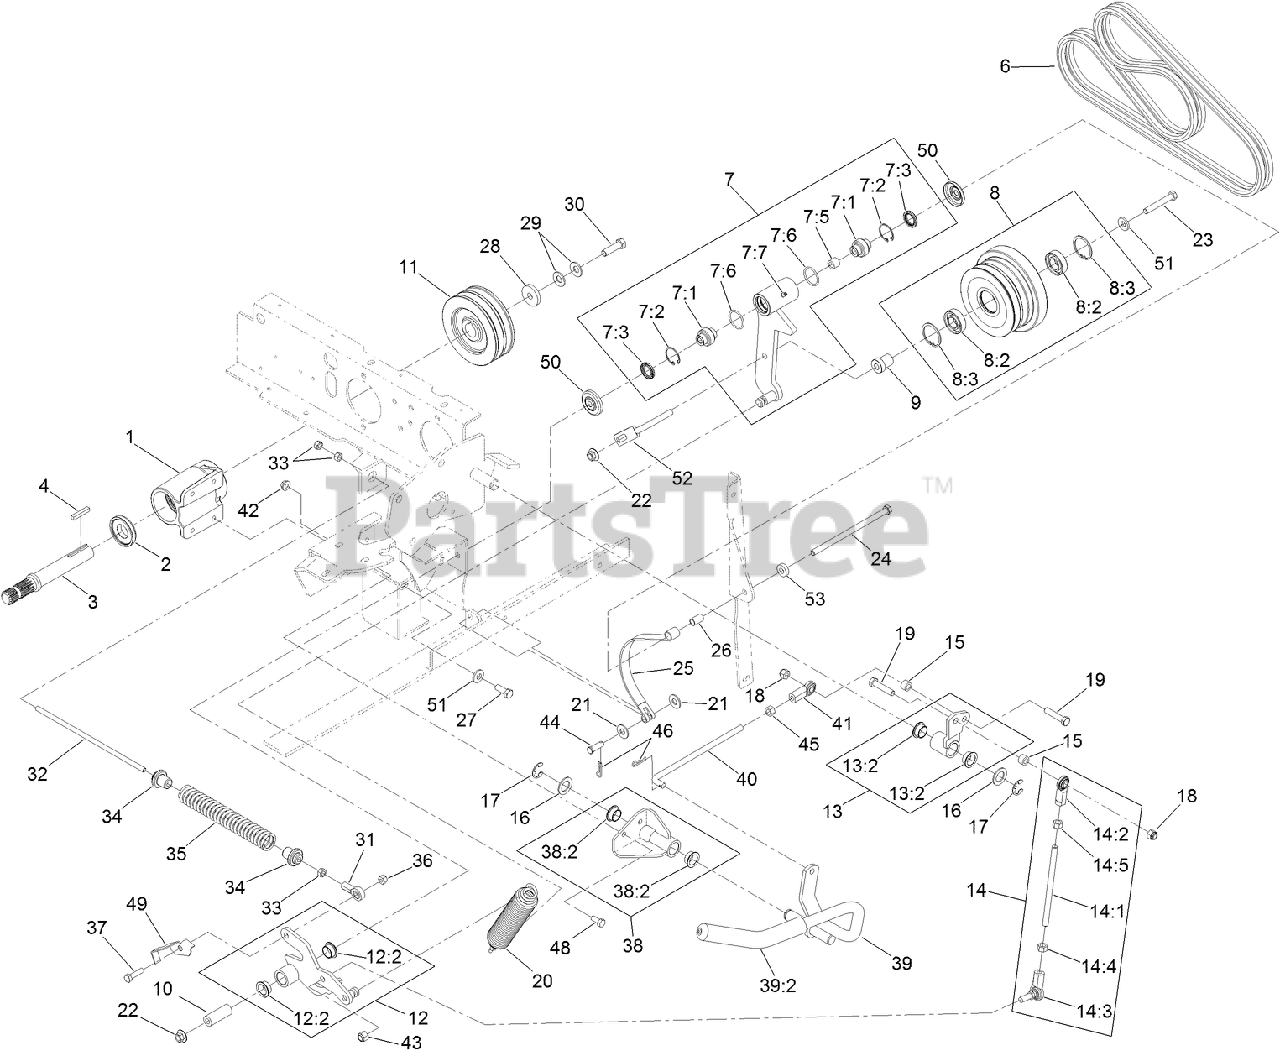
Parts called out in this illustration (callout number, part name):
1	JACKSHAFT ASM
2	SPACER-GUARD, BOTTOM
3	JACKSHAFT
4	KEY-SQUARE
6	BELTS-PAIR, MATCHED
7	IDLER PIVOT ASM
7:1	BEARING-SPHERICAL
7:2	RING-SNAP
7:3	SEAL-LIP, SINGLE
7:5	BUSHING-LEVER, LIFT
7:6	O-RING
7:7	FITTING-GREASE
8	IDLER SHEAVE ASM
8:2	BEARING-BALL
8:3	RING-RETAINING
9	SPACER-IDLER
10	BUSHING
11	SHEAVE
12	ARM ASM
12:2	BUSHING-BRONZE
13	ARM ASM
13:2	BUSHING-BRONZE
14	CLUTCH LINK ASM
14:1	ROD-LINKAGE
14:2	JOINT-BALL END, LH
14:3	BALLJOINT-RH
14:4	NUT-HEX
14:5	NUT-HEX, LH
15	SPACER
16	WASHER
17	E-RING
18	NUT-LOCK, NI
19	SCREW-HH
20	SPRING-EXTENSION
21	WASHER-FLAT
22	NUT-HF
23	SCREW-HH
24	SCREW-HH
25	BAND-BRAKE
26	SPACER
27	SCREW-HH
28	WASHER-CLUTCH
29	WASHER-SPRING
30	SCREW-HH
31	BALLJOINT-RH
32	LINKAGE-ROD, PTO BRAKE
33	NUT-HEX
34	BUSHING-SPRING
35	SPRING-BRAKE
36	NUT-LOCK, NI
37	SCREW-HH
38	PIVOT ASM
38:2	BUSHING-BRONZE
39	PTO HANDLE ASM
39:2	GRIP-LEVER, CONTROL
40	LINK-HANDLE
41	JOINT-BALL, END
42	NUT-HF
43	NUT-LOCK
44	PIN-CLEVIS
45	NUT-HEX
46	PIN-COTTER
48	SCREW-HH
49	SWITCH-FLAG
50	GUARD-TOP
51	WASHER-BELLEVILLE
52	GUIDE-BELT
53	SPACER
